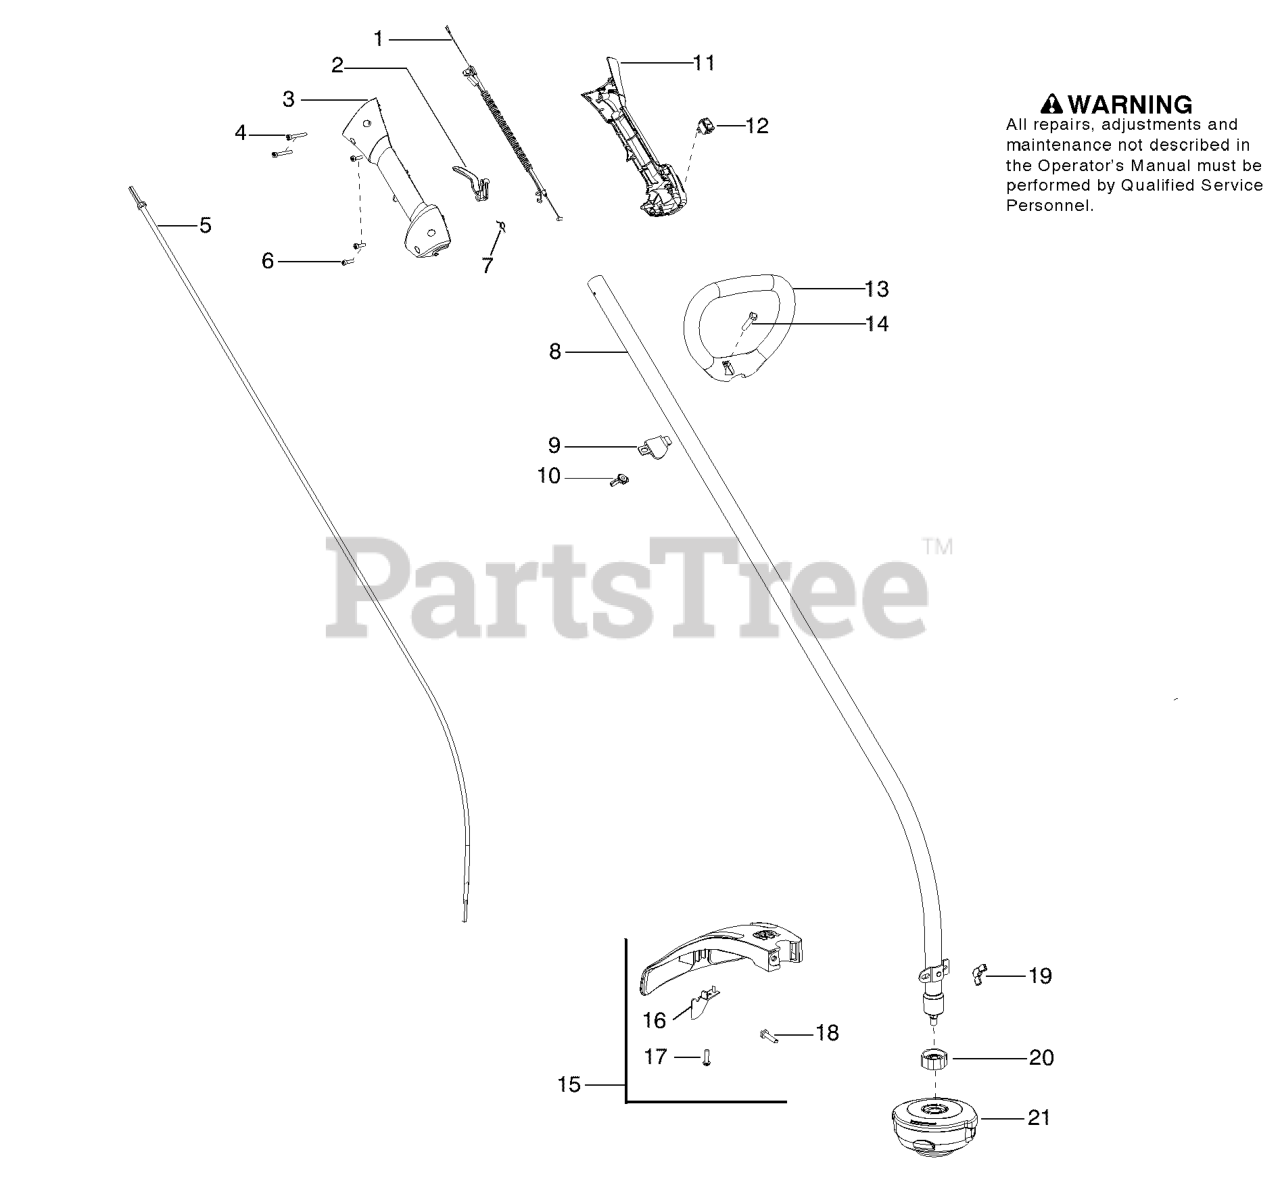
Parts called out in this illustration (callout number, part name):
1	Assy-Cable/Wire Harness
2	TRIGGER THROTTLE
3	HOUSING-THROTTLE (RH)
5	Flexshaft
6	SCREW M4 X 1.75 PT 16MM
7	SPRING TRIGGER
8	DRIVESHAFT KIT
9	CLAMP ASSIST HANDLE
10	WINGNUT, TYPE 2
11	HSG THROTTLE LH
12	KIT SWITCH
13	HANDLE ASSIST
14	BOLT, TYPE 2
15	TRIMMER GUARD 128C
16	KIT - LIMITER - LINE
18	BOLT, TYPE 2
19	WINGNUT, TYPE 2
21	T25 TRIMMER HEAD 3/8 RH
